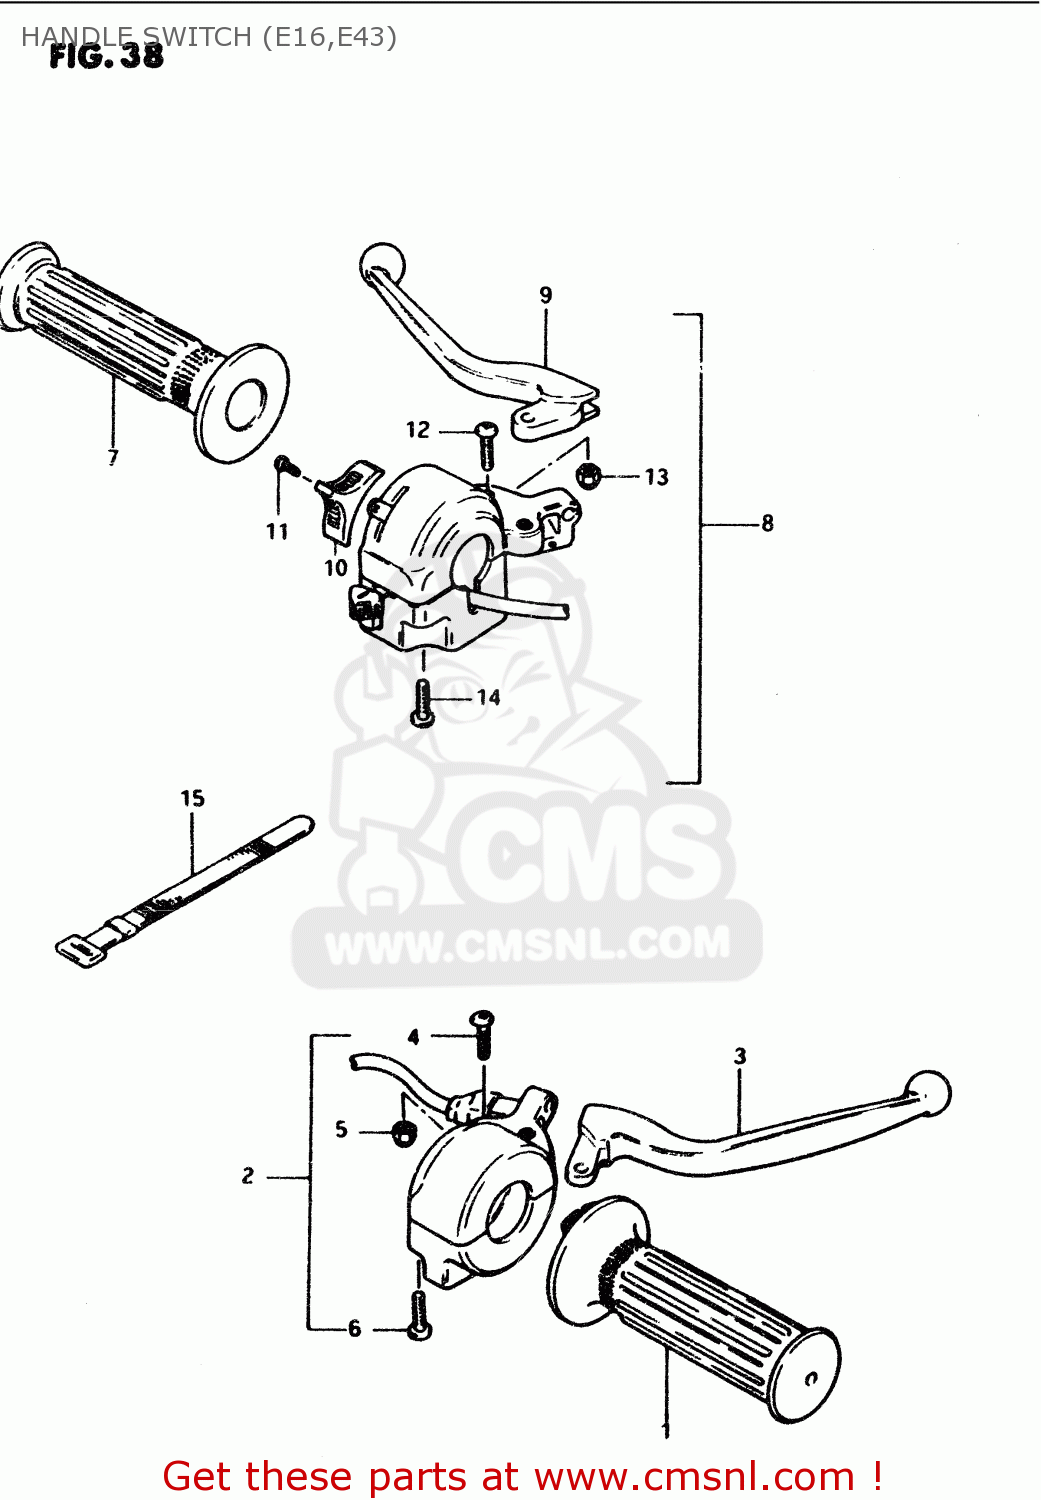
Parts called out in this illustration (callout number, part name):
1	GRIP,THROTTLE
2	BRAKE LEVER & SWITCH ASSY
3	LEVER
4	BOLT,LEVER PIVOT
5	NUT
6	SCREW
7	GRIP,L
8	LEVER ASSY,CLUTCH
9	LEVER
10	KNOB
11	SCREW
12	BOLT,LEVER PIVOT
13	NUT
14	SCREW
15	CLAMP(L:120)
